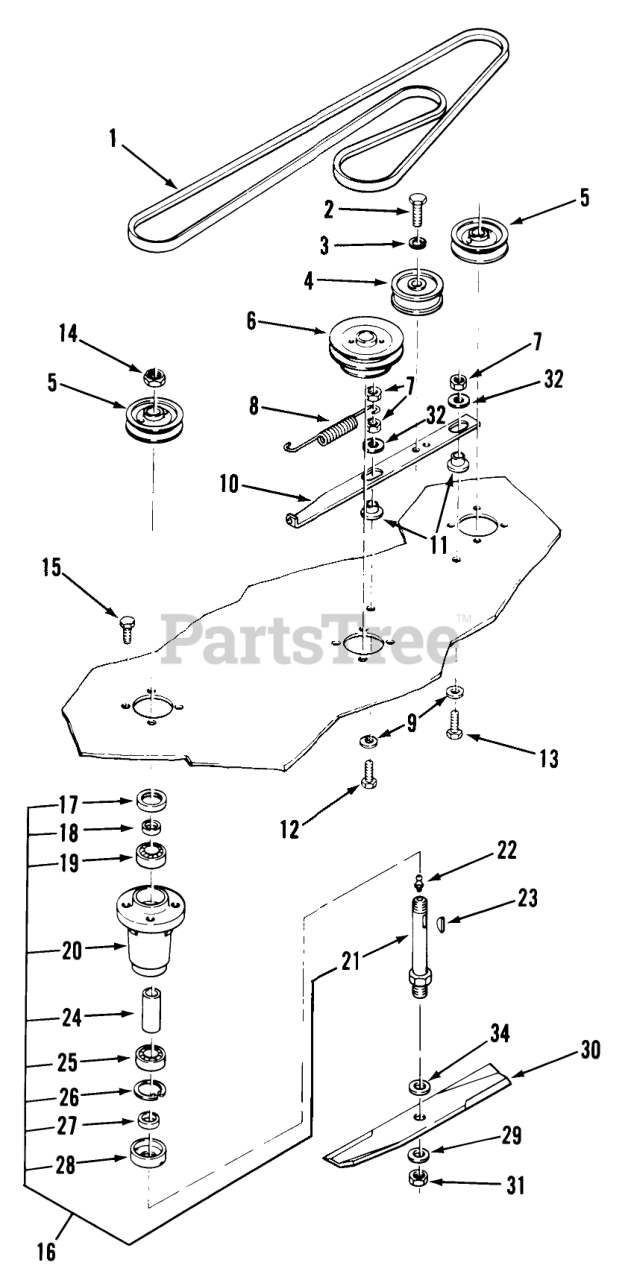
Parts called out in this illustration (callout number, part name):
1	V-BELT
2	BOLT HEX SPECIAL
3	LOCKWASHER
4	Idler Pulley
5	PULLEY-BLADE DRIVE
6	PULLEY-48 MOWER SPDL
7	NUT
8	SPRING-EXTENSION
9	WASHER
10	BAR-IDLER SUPPORT
11	SPACER-BUSHING
12	Bolt
13	Bolt
14	Nut
15	Bolt
16	Spindle Assembly
18	SPACER-SEAL
19	BEARING-BALL
20	HOUSING-SPINDLE
21	7" X 3/4" SHAFT.JAK
22	Zerk
23	Hi-Pro Key 3/16 x 5/8
24	SPACER
25	BEARING-BALL
26	Ring-Snap
27	SPACER-BLADE
28	CUP-SPINDLE
29	SpeciaI Washer
30	BLADE KIT (3 PACK)
31	Nut
32	WASHER
34	Washer
